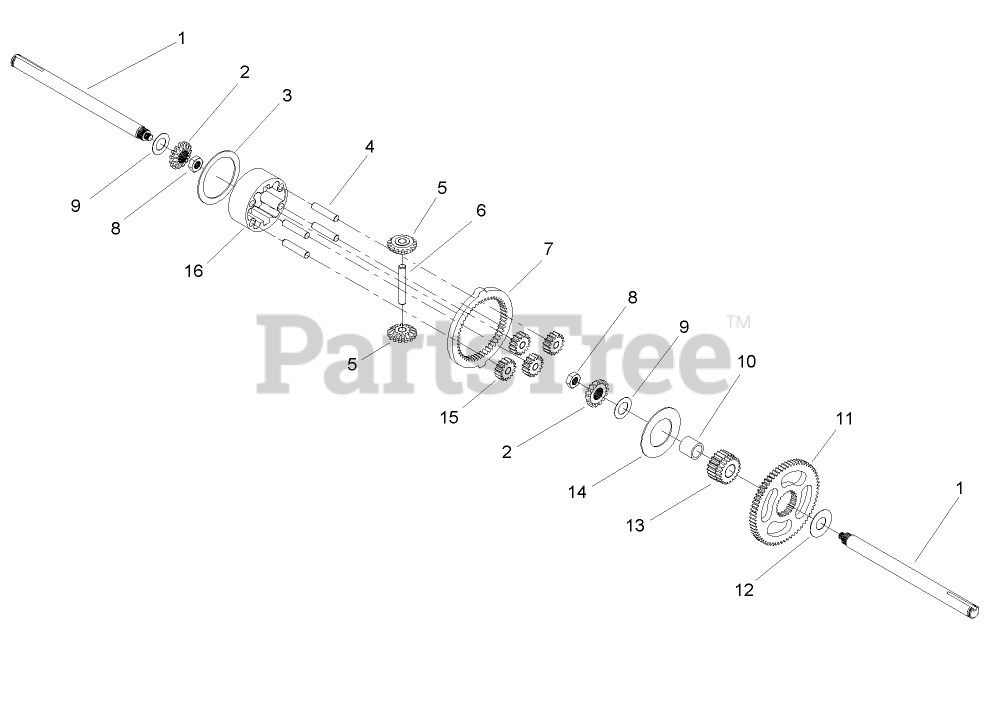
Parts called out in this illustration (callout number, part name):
1	SHAFT-AXLE
2	GEAR-MITER
3	PLATE-THRUST
4	PIN-CARRIER
5	GEAR-MITER
7	GEAR-RING, 51T
8	NUT-HJ
9	WASHER
10	BEARING-SLEEVE
11	GEAR-SPUR, 67T
12	WASHER
13	GEAR-SUN, 21T
14	PLATE-THRUST, PLANET
15	GEAR-PLANET, 15T
16	CARRIER-PLANETARY
